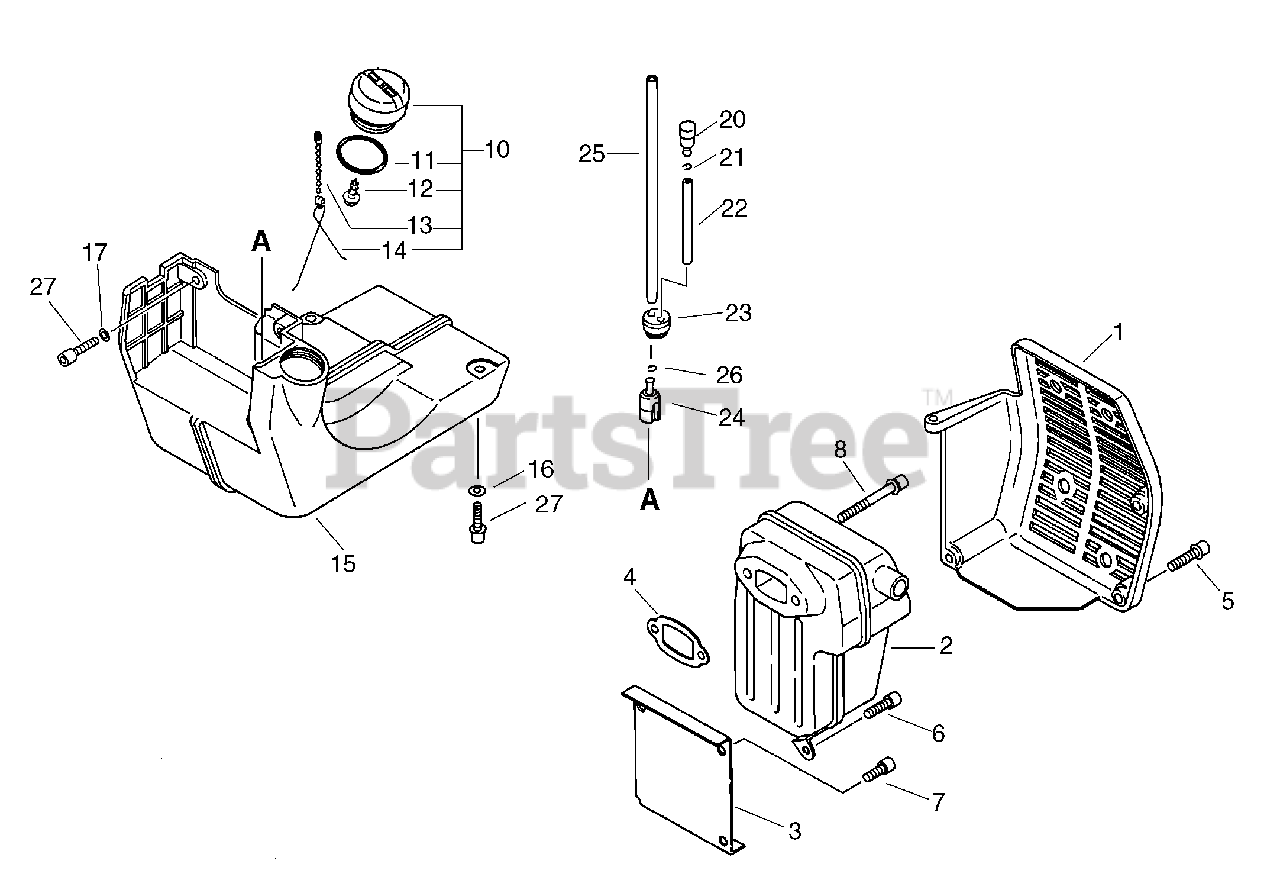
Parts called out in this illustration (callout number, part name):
1	COVER, EXHAUST
2	MUFFLER
3	SHIELD, EXHAUST
4	GASKET, EXHAUST
5	SCREW - 5X18
6	SCREW - 5X16
7	SCREW - 5X10
8	SCREW - 5X75
10	CAP ASSY
11	O-RING - 32
12	SCREW - 3X8
13	CONNECTOR, CAP
14	RETAINER
15	TANK, FUEL
17	WASHER - 5
20	VENT, FUEL TANK
21	CLIP - 6
22	PIPE - FUEL
23	GROMMET
24	FILTER, FUEL
25	PIPE - FUEL
26	CLIP - 6.5
27	SCREW - 5X16
